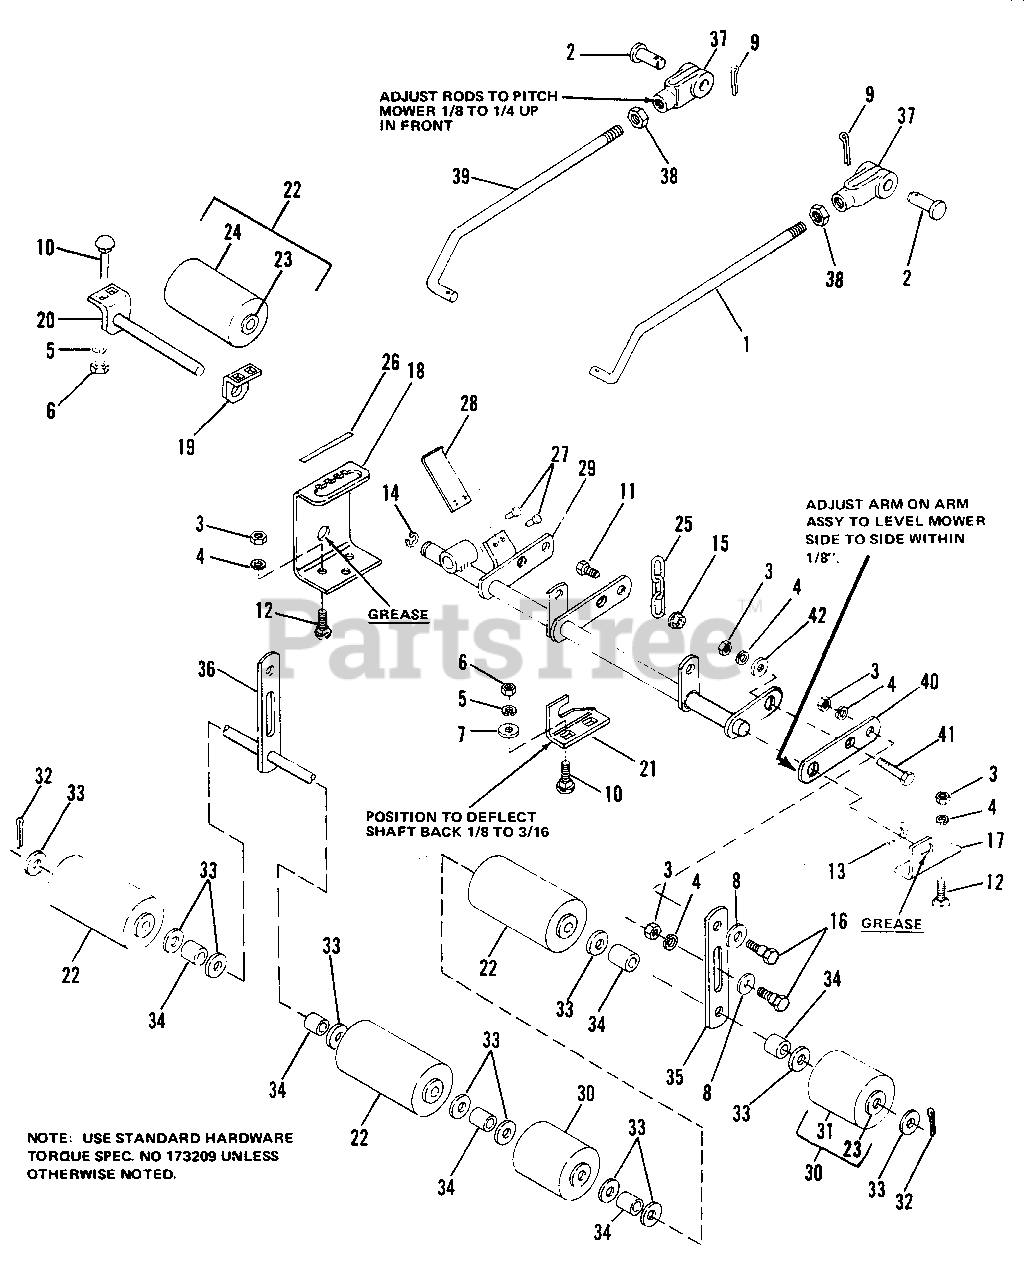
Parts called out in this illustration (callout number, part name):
1	ROD, Mower Adj., L.H.
2	PIN, Yoke
3	NUT, Hex, 3/8-16
4	LOCKWASHER, 3/8
5	LOCKWASHER, 5/16
6	NUT, Hex, 5/16-18
7	WASHER, 5/16
8	WASHER, 1/2
9	PIN, Cotter, 1/8 x 1
10	BOLT, Carriage, 5/16-18 x 3/4
11	CAPSCREW, Hex, 5/16-18 x 1
12	BOLT, Carriage, 3/8-16 x 3/4
14	RING, Retaining
15	LOCKNUT, Flange, 3/8-16
16	BOLT, Shoulder, 3/8-16 X 1.34
17	BRACKET, Pivot, L.H.
19	BRACKET, Center, Roller
20	SHAFT ASSY., Center, Roller
21	BRACKET, Lift
22	ROLLER ASSY., Large
24	ROLLER
25	CHAIN, Lift
26	DECAL, Mower Height
29	ARM ASSY. Mower
30	ROLLER ASSY., Small
31	ROLLER
32	PIN, Cotter, 3/16 x 1
33	WASHER, 25/32 x 1-1/4
34	SPACER, .66 ID
35	BAR, Roller
36	SHAFT ASSY., Roller
38	NUT, Hex, Jam, 1/2-20
39	ROD, Mower Adj. R.H.
40	ARM, Rear, Mower
41	CAPSCREW, Hex, 3/8-16 x 1-1/4
42	WASHER, 13/32 x 1
